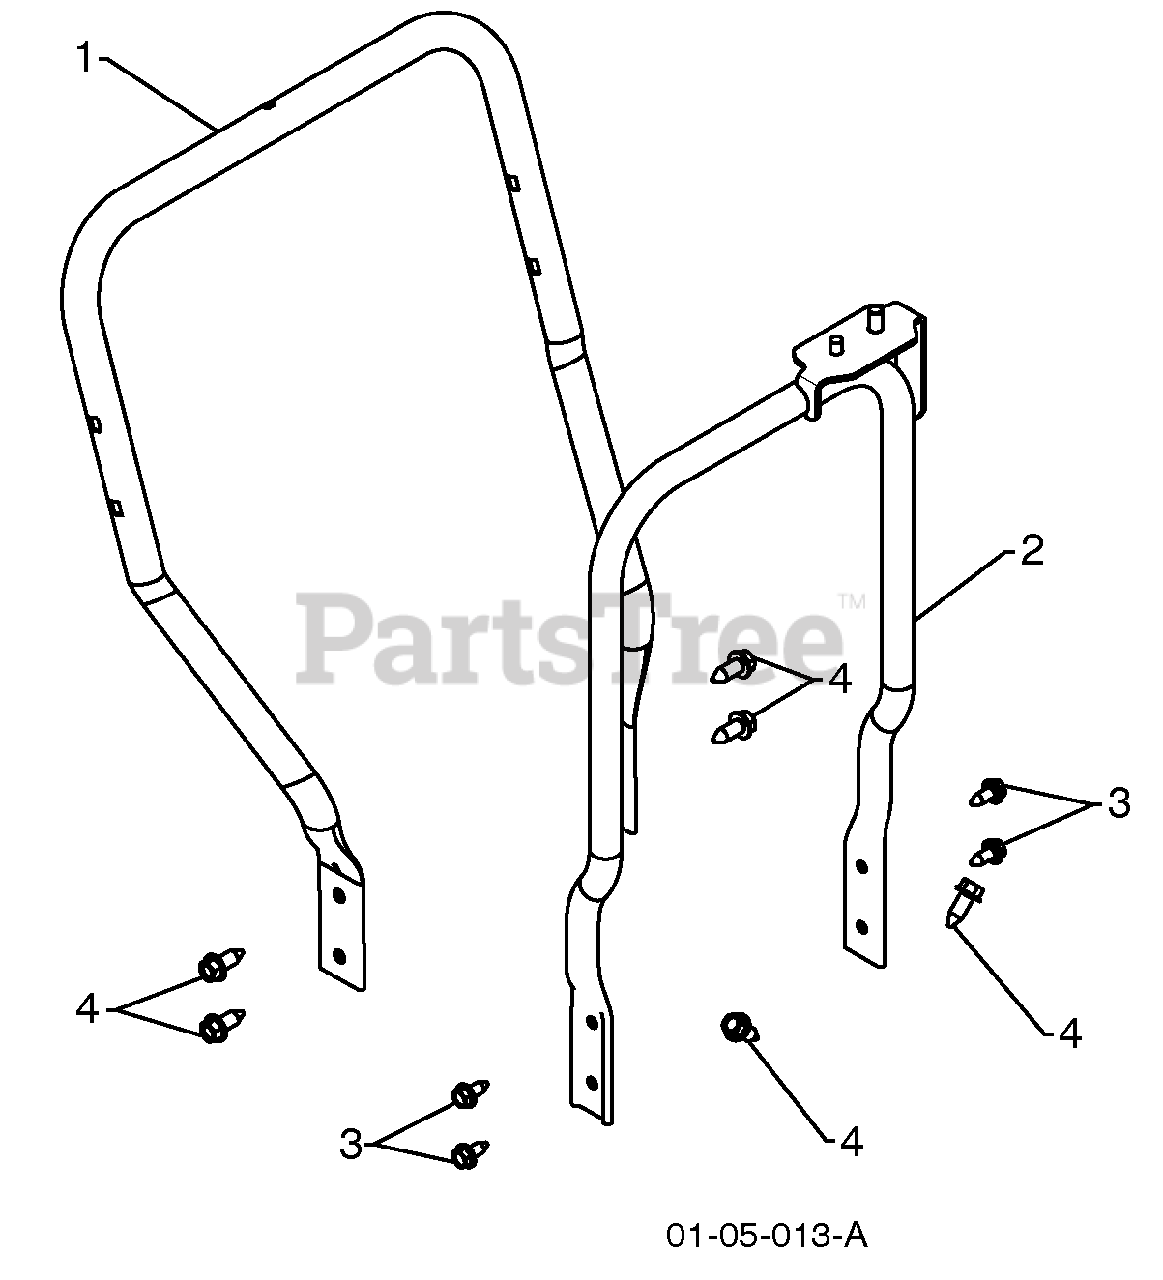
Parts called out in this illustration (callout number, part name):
1	LOWER HANDLE
2	PIVOT SUPPORT WELDMENT
3	SCREW 5/16-18 X .750
4	SCREW 3/8-16 X 1.00
